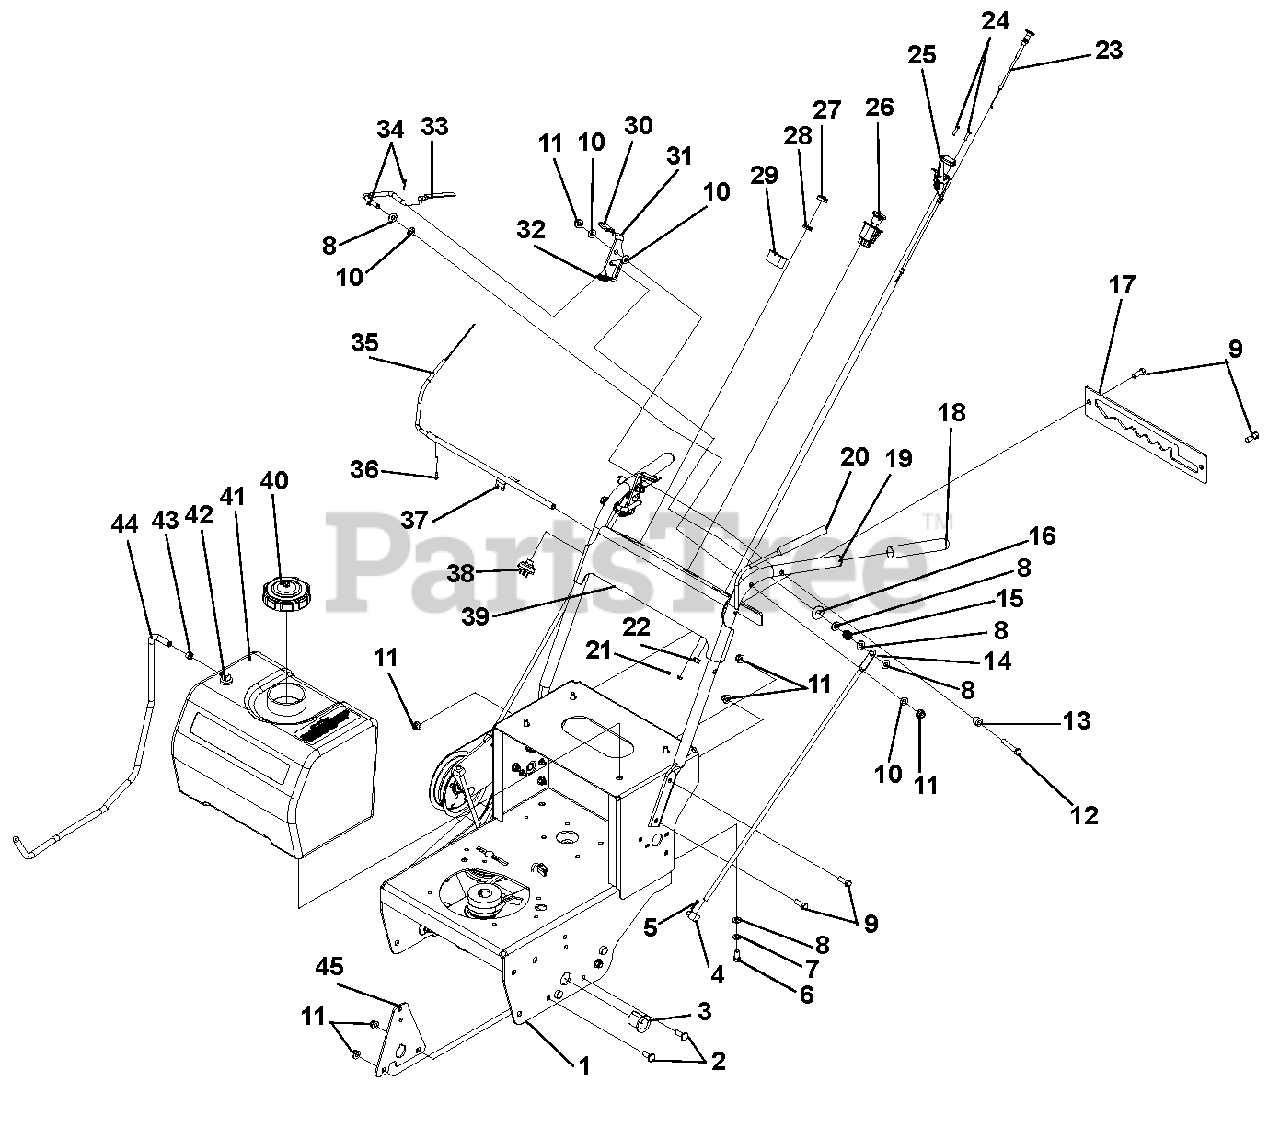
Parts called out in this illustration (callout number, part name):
1	Wasp GearWalk Frame with Decal
2	Bolt, .375-16 x1.00 Round Head Square Neck 5
3	Bushing, Flange 1.010 x 1.38 x 1.4 x 1.65
4	Swivel, .375-24
5	Pin, Hair
6	Bolt, .375-16 x .750 Hex
7	Washer, .375 Medium Spring Lock
8	Washer, Flat .406 x .813 x .065
9	Bolt, .375-16 x 1.00 Hex
10	Washer, Flat Nylon .375 x .75 x .060
11	Nut, Nyloc Flange, .38-16
12	Bolt, .375-16 x 2.50 Hex
13	Bushing, Sleeve .391 x .688 x .52 Promaster
14	Rod, Steering Pro Walk
15	Spring, Compression .045 x .600 x .750 WLD7.5
16	Washer, Flat-Steel, .50 x 1.25 x .083
17	Plate, Shift Lever Detent
18	Grip, Handlebar
19	Caplug, Handlebar
20	Lever, Left Hand-Operator Presence
21	Locknut, 10-24 Nyloc
22	Nut, .38-24 Standard Hex
23	Cable, Choke
24	Screw, Machine 10-24 x .75 Hex Washer Head
25	Cable, Throttle with Liner
26	Switch, PTO
27	Cap, Ignition Switch
28	Nut, Panel .562-24
29	Plug, Hour Meter
30	Grip, Thumb Latch
31	Latch, Left Hand Thumb
32	Spring, Tension .041 x .500 x 1.750
33	Lever, Hand Control Left Hand
34	Pin, Cotter .094 x .750 EXTP
35	Lever, Right Hand-Operator Presence
36	Screw,Tapping 8-32 x .50 Hex Washer Head Thread Rolling
37	Weldament, Pivot Tube
38	Key, Switch
39	Wasp Gear Walk Handlebar w/Decals
40	Cap, Fuel
41	Tank, Fuel EverRide Walk
42	Fitting, Tank
43	Clamp, Hose- .50 Spring
44	Hose, Fuel .25 x 30.00
45	Plate, Axle/Bearing Mounting
